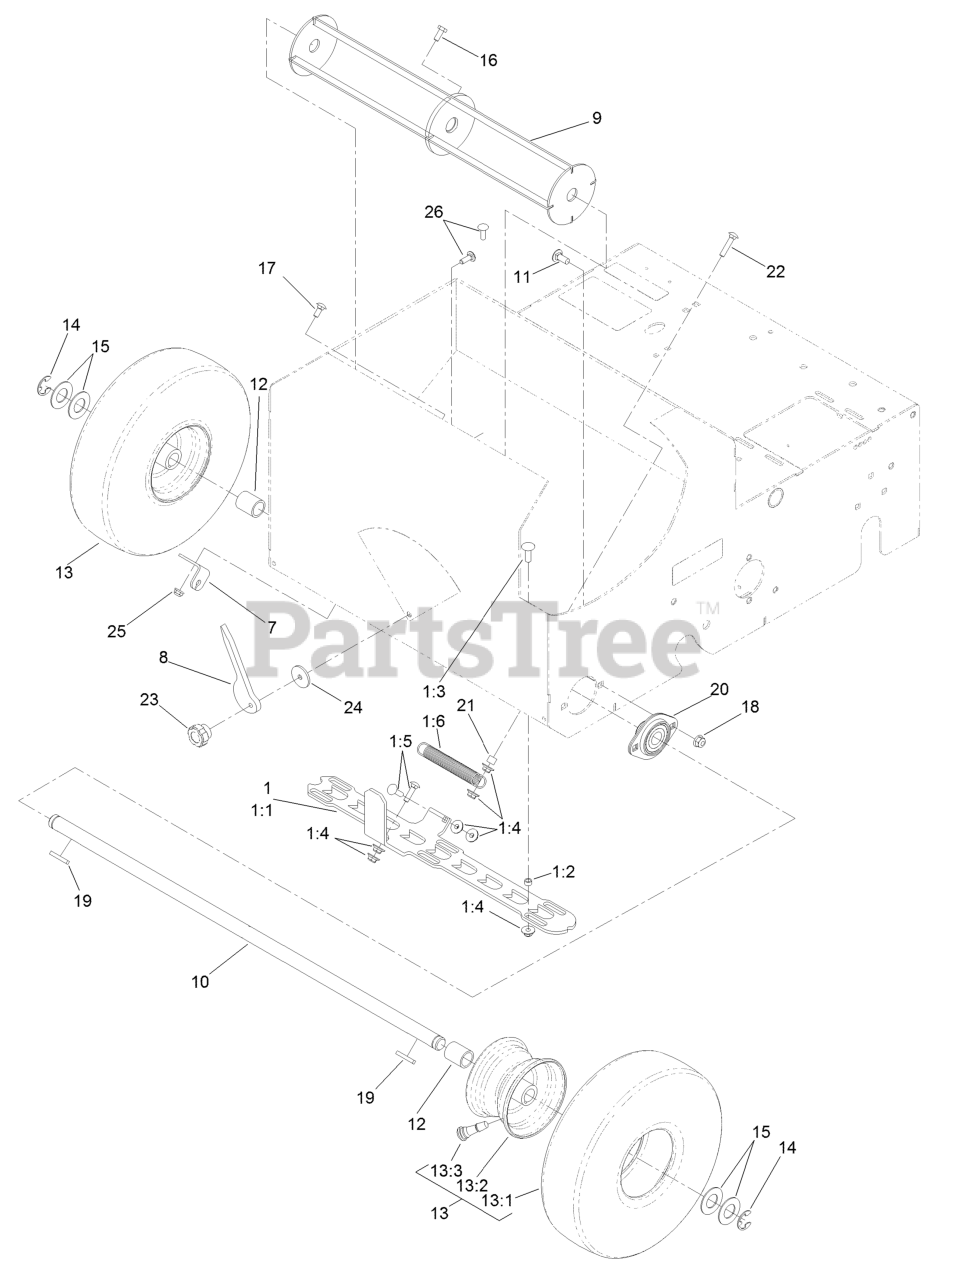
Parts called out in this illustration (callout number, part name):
1	SEED GATE KIT
1:1	GATE-SEED
1:3	BOLT-CARR
1:5	SCREW-CARR
1:6	SPRING-EXTENSION
7	BRACKET-FLOW, SEED
8	GAUGE-FLOW, SEED
10	AXLE-FRONT
11	SCREW-CARR
13	WHEEL ASM
13:2	WHEEL-RIM
13:3	VALVE
15	WASHER-FLAT
16	SCREW-HH
17	SCREW-CARR
18	NUT-HF, NI
19	KEY-SQUARE
20	BEARING
22	SCREW-CARR
23	KNOB-CHUTE
24	WASHER
26	BOLT-CARR
